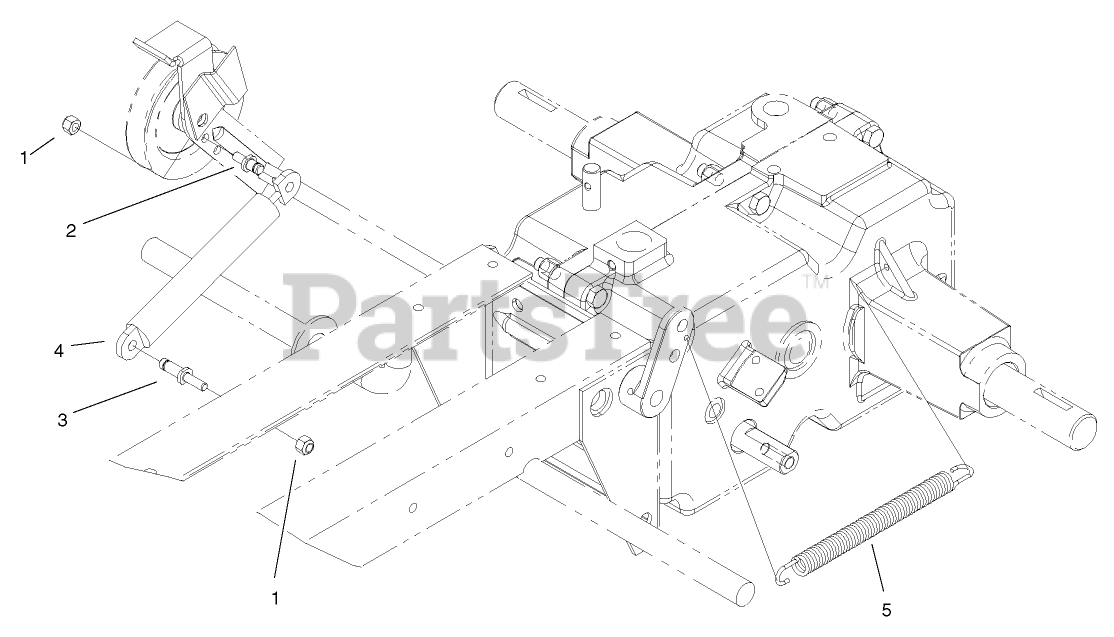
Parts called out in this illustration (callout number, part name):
1	NUT-LOCK, NI
2	PIN-DAMPER, CLUTCH ARM
3	PIN-DAMPER, CLASSIC FRAME
4	DAMPER-GAS
5	SPRING-CLUTCH
